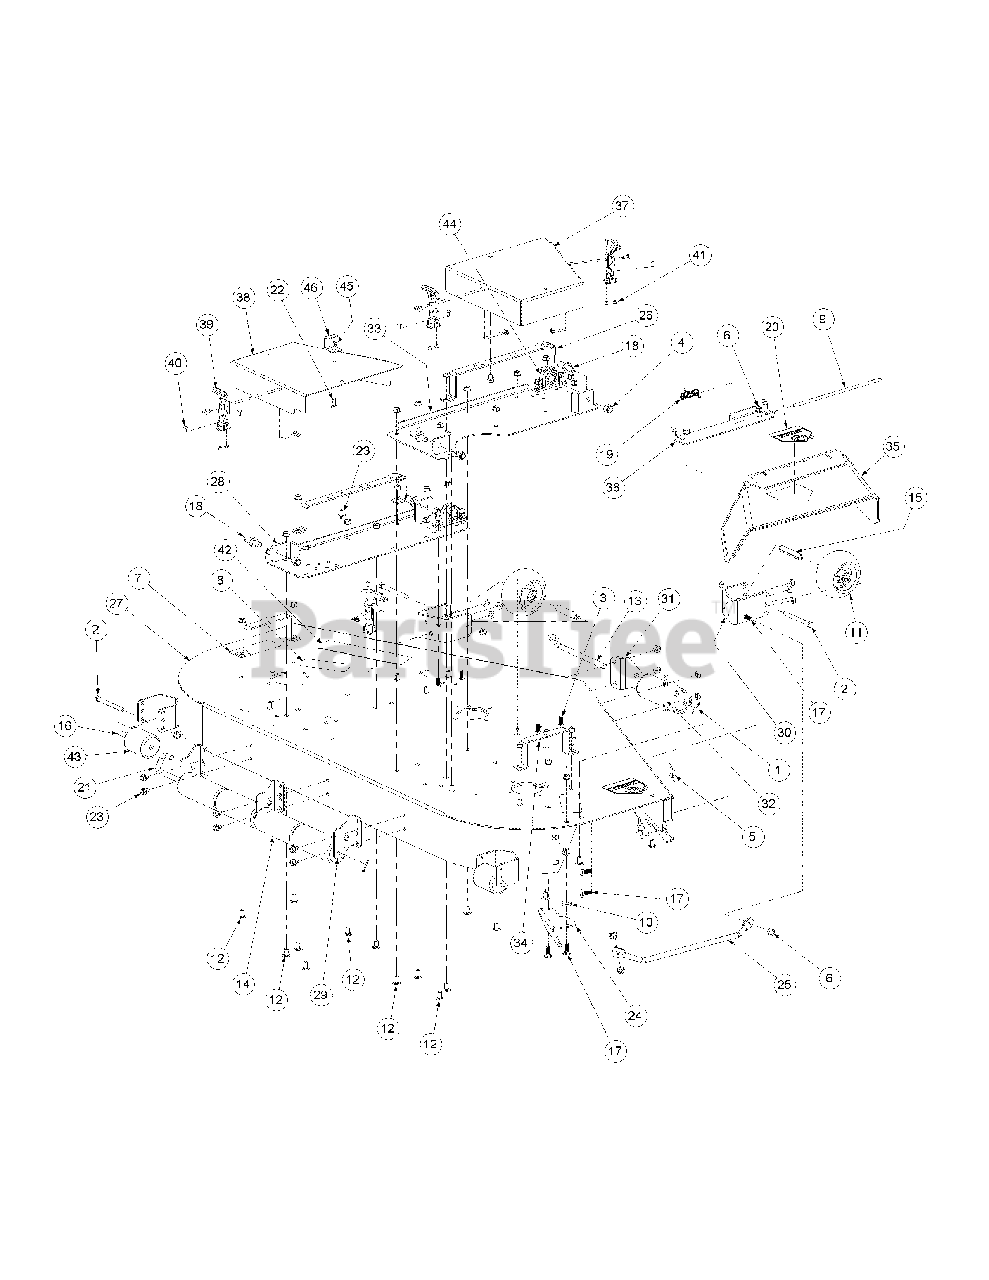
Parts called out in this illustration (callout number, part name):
1	Cotter Pin, .125 Dia. x 1.0
2	Hex Cap Screw, 3/8-16, 3.75
3	Carriage Screw, 3/8-16 x 1.25
4	Lock Nut, Nylon Insert, 1/2-13
5	Label, 60"
6	Flange Lock Hex Nut, 3/8-16
7	Decal, Rotating Blade
8	Decal, Warning Shield Missing
9	Chute Deflector Rod
10	Idler Washer
11	Complete Wheel, 5.00 Dia.
12	Carriage Bolt, 3/8-16 x .75 Lg.
13	Roller Pin, 1/2 Dia. x 7.31 Lg.
14	Front Roller
15	Wheel Spacer
16	Spacer, .385 x .50 x 3.045
17	Carriage Bolt, 3/8-16 x 1
18	Pin, 5/8 Dia. x 1.2 Lg.
19	Torsion Spring, 0.4ID x 2.16Lg
20	Decal, Danger Hand and Feet
21	Roller Pin
22	Hex Cap Screw, 5/16-18 x .75
23	Hex Index Washer Screw, 3/8-16, .5
24	Chute Bracket
25	Finger Guard
26	Belt Cover Support
27	60 Deck Assembly
28	Left Hand Mount Deck Bracket Assembly
29	Deck Roller Mount Bracket
30	Anti-Scalp Wheel Front Mount Bracket
33	Right Hand Deck Bracket Assembly
34	Outer Belt Cover Support Assembly
35	Chute Deflector
36	Chute Deflector Bracket
37	Right Hand Deck Belt Cover
38	Left Hand Deck Belt Cover
39	T-Handle Latch Draw
40	Phillips Head Screw, 10-32
41	Lock Nut, Nylon Insert, 10-32
42	Commercial Mower Label
43	Grass Catcher Roller
44	Pillow Block
45	Nut, 5/16-18, Hex Flange Lock
46	Stop Bracket
